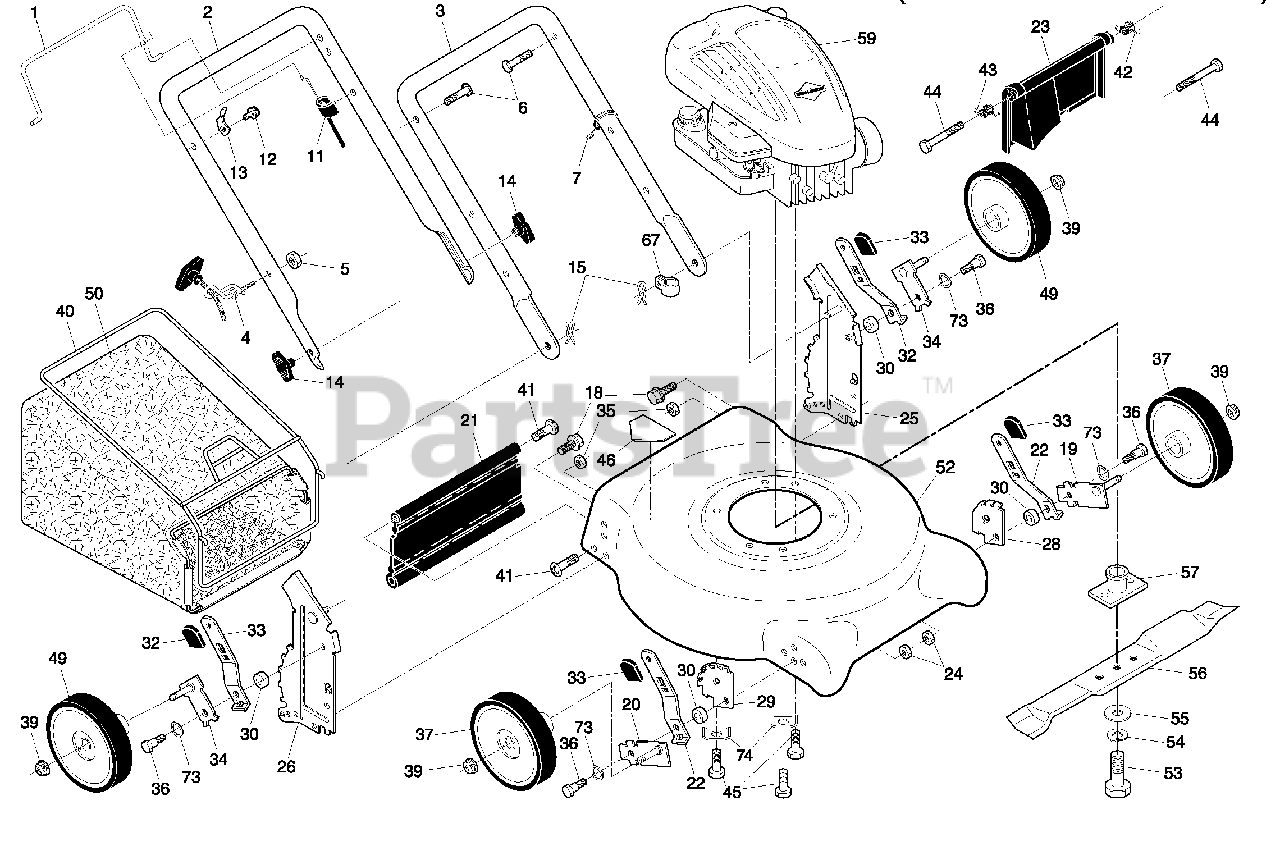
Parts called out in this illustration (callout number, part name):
1	Control Bar
2	Upper Handle
3	Lower Handle
4	Rope Guide
6	Handle Bolt
7	Wire Tie
11	Cable, Engine Zone Control
12	Hex Washer Head Screw
13	Up-Stop Bracket
14	Knob, Handle
15	Hairpin Cotter
18	Screw
19	Axle Arm Assembly, Front, LH
20	Axle Arm Assembly, Front, RH
21	Rear Skirt
22	Selector Spring, Front
23	Rear Door Assembly
24	Nut, Hex 5/16-18
25	Handle Bracket Assembly, LH
26	Handle Bracket Assembly, RH
28	Wheel Adjusting Bracket, Front, LH
29	Wheel Adjusting Bracket, Front, RH
30	Spacer
32	Selector Spring, Rear
33	Selector Knob
34	Axle Arm Assembly, Rear, LH
35	Locknut, Hex 5/16-18
36	Shoulder Bolt 5/16-18
37	Wheel & Tire Assembly, Front 7 x 1-3/4
39	Flanged Locknut, Hex
40	Frame, Grassbag
41	Hinge Screw
42	Spring, Rear Door, LH
43	Spring, Rear Door, RH
44	Bolt, Rear Door
45	Hex Head Thread Rolling Screw 3/8-16 x 1
46	Danger Decal
49	Wheel & Tire Assembly, Rear 8 x 1-3/4
50	Grassbag
52	Kit, Lawn Mower Housing
53	Hex Head Screw 3/8-24 x 1-3/8 Grade 8
54	Helical Lockwasher
55	Hardened Washer
56	21" Blade
57	Blade Adapter
67	Clip, Cable
73	Washer, Curved, Cylindrical
74	Washer, Special, Engine
74	Operator's Manual, English
74	Operator's Manual, French
74	Repair Parts Manual, English / French
